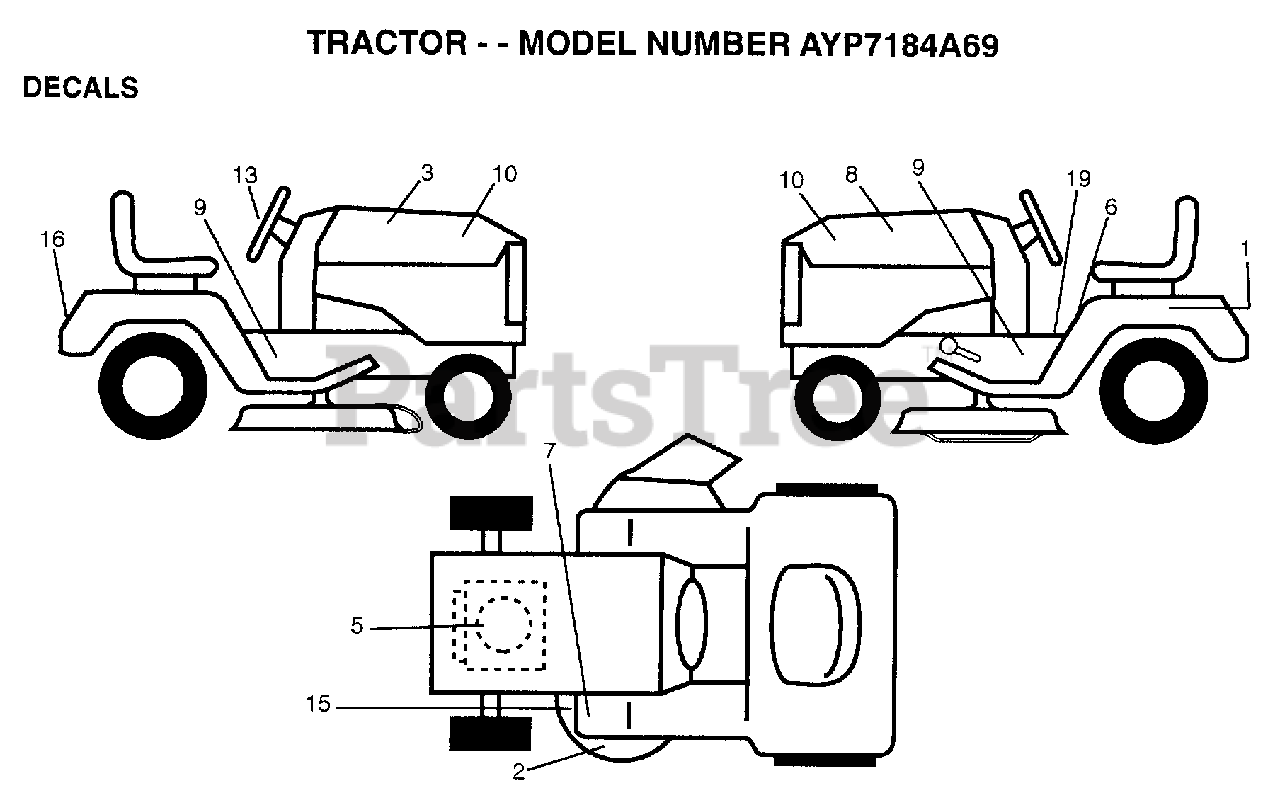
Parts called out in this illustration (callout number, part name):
1	DECAL.BTRY.DANGER
2	DECAL DECK WIZ +
3	DECAL.HD.RH.WIZAR
5	DECAL ENGINE
6	DECAL
8	DECAL.HD.LH.WIZAR
9	DECAL CHASSIS WIZ
10	DECAL.INS.HD.WIZA
13	DECAL.INS.STRG.WL
15	DECAL
